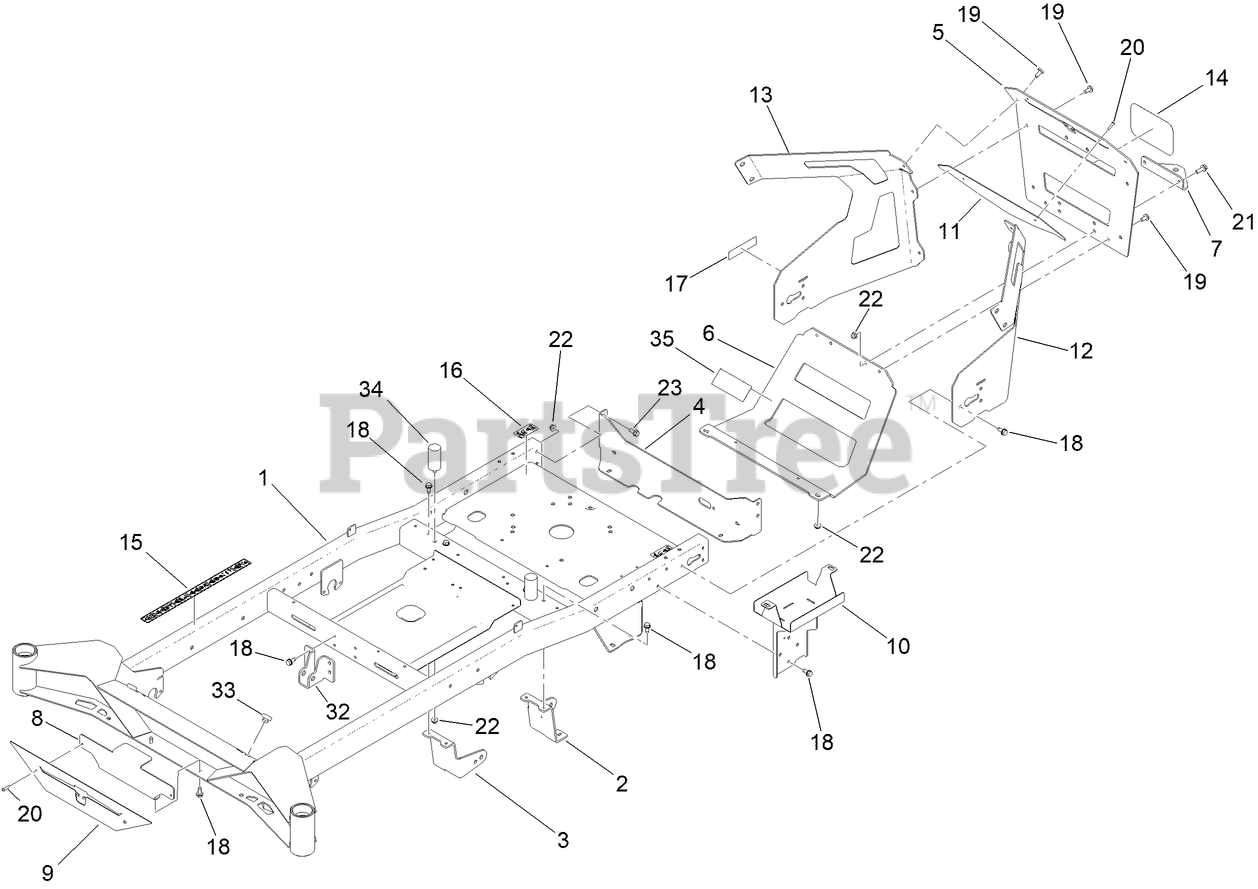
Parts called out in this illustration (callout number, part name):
1	SERVICE ASM-FRAME, TITAN
2	MOUNT-DRIVE, LH
3	MOUNT-DRIVE, RH
4	PLATE-MOUNT
5	GUARD-ENGINE
6	GUARD-MUFFLER
7	BRACKET-HITCH
8	PLATE-BACKER
9	LOGO-PLATE-FRONT
10	WA-BATTERY MOUNT
11	PLATE-BACKER
12	GUARD-ENGINE LH
13	GUARD-ENGINE-RH
14	DECAL
15	DECAL-WARNING
16	DECAL-BYPASS
17	DECAL-SPARK ARRESTER
18	SCREW-HWHTF
20	RIVET-TRIFOLD
21	SCREW-HHF
22	NUT-HF
23	SCREW-HHF
32	BRACKET-MOUNT DAMPER, LOWER
33	BUMPER-RUBBER
34	BUMPER-RUBBER
35	TAPE-HEAT
